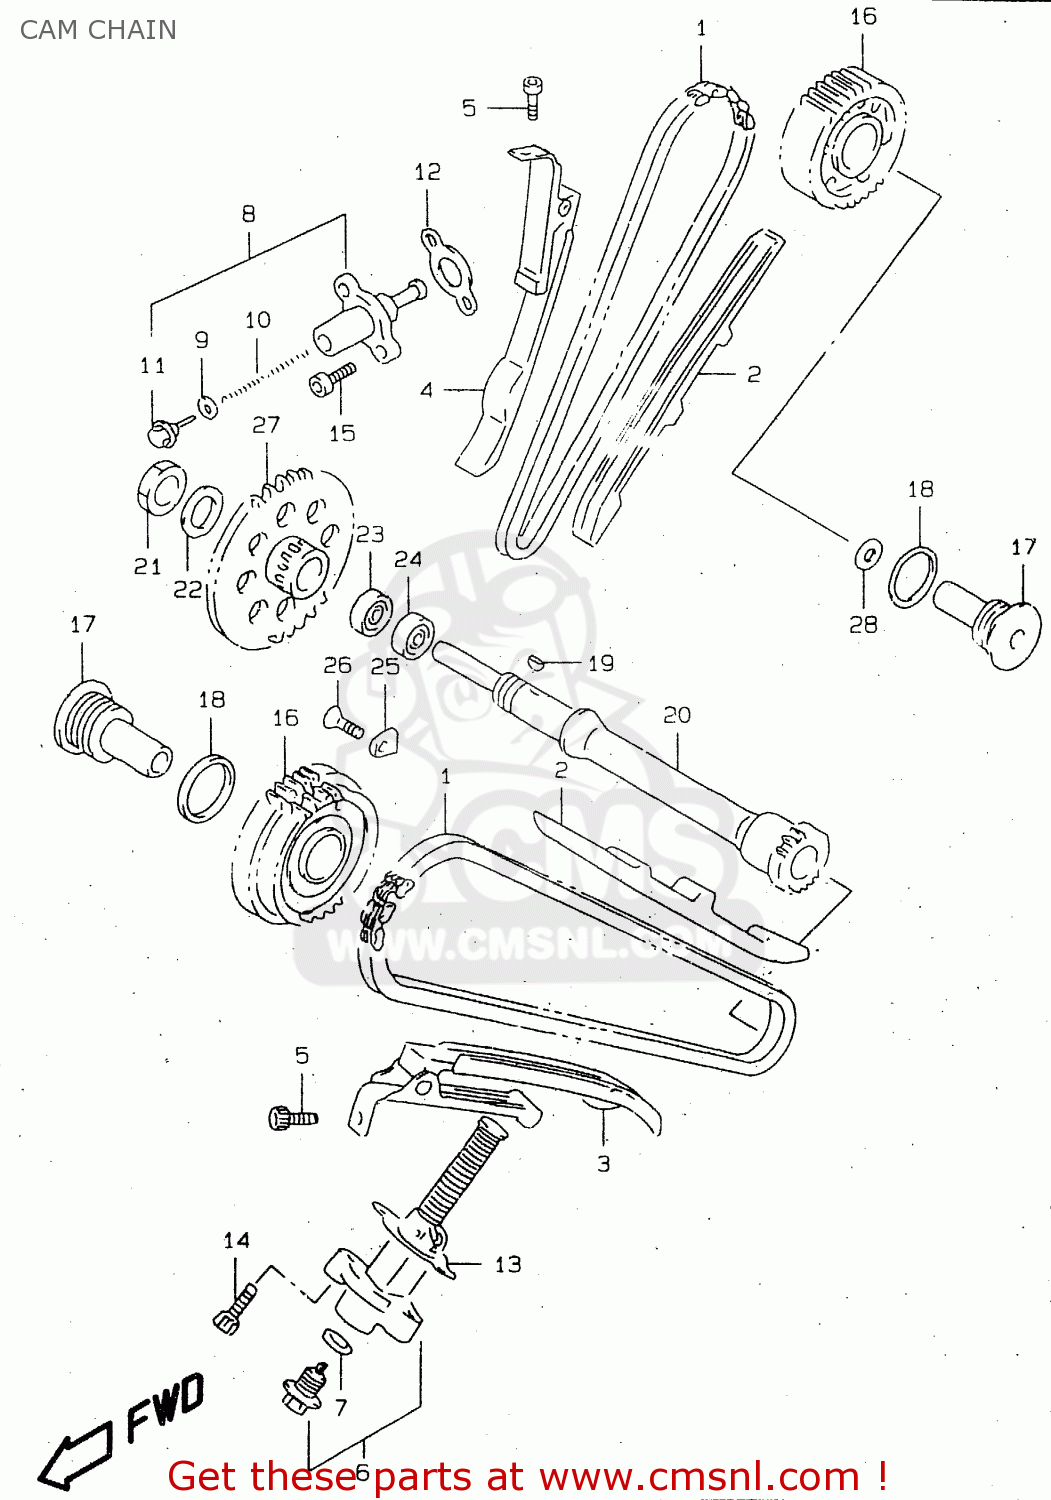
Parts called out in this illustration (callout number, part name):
1	CHAIN,CAMSHAFT DRIVE
2	GUIDE,CAM CHAIN
3	TENSIONER,CAM CHAIN FR
4	TENSIONER,CAM CHAIN RR
5	BOLT
6	ADJUSTER ASSY,TENSIONER FR
7	GASKET(12X21X2) (NAS)
8	ADJUSTER ASSY,TENSIONER
9	O RING
10	SPRING
11	PLUG,ADJUSTER
12	GASKET,TENSIONER ADJUSTER (NAS)
13	GASKET,TENSIONER ADJUSTER (NAS)
14	BOLT,CL.COVER
15	BOLT,CRKCASE,R
16	GEAR,CAM CHAIN IDLER NO.2
17	SHAFT,IDLER NO.2
18	GASKET(26.5X30.5X1) (NAS)
19	KEY
20	SHAFT,IDLER
21	NUT
22	SHIM(16X26X1.5)
23	BEARING
24	BEARING(25X47X10)
25	RETAINER,COUNTER BEARING,R
26	SCREW
27	SPROCKET,IDLER NO.1
28	SHIM(15X24X1)
